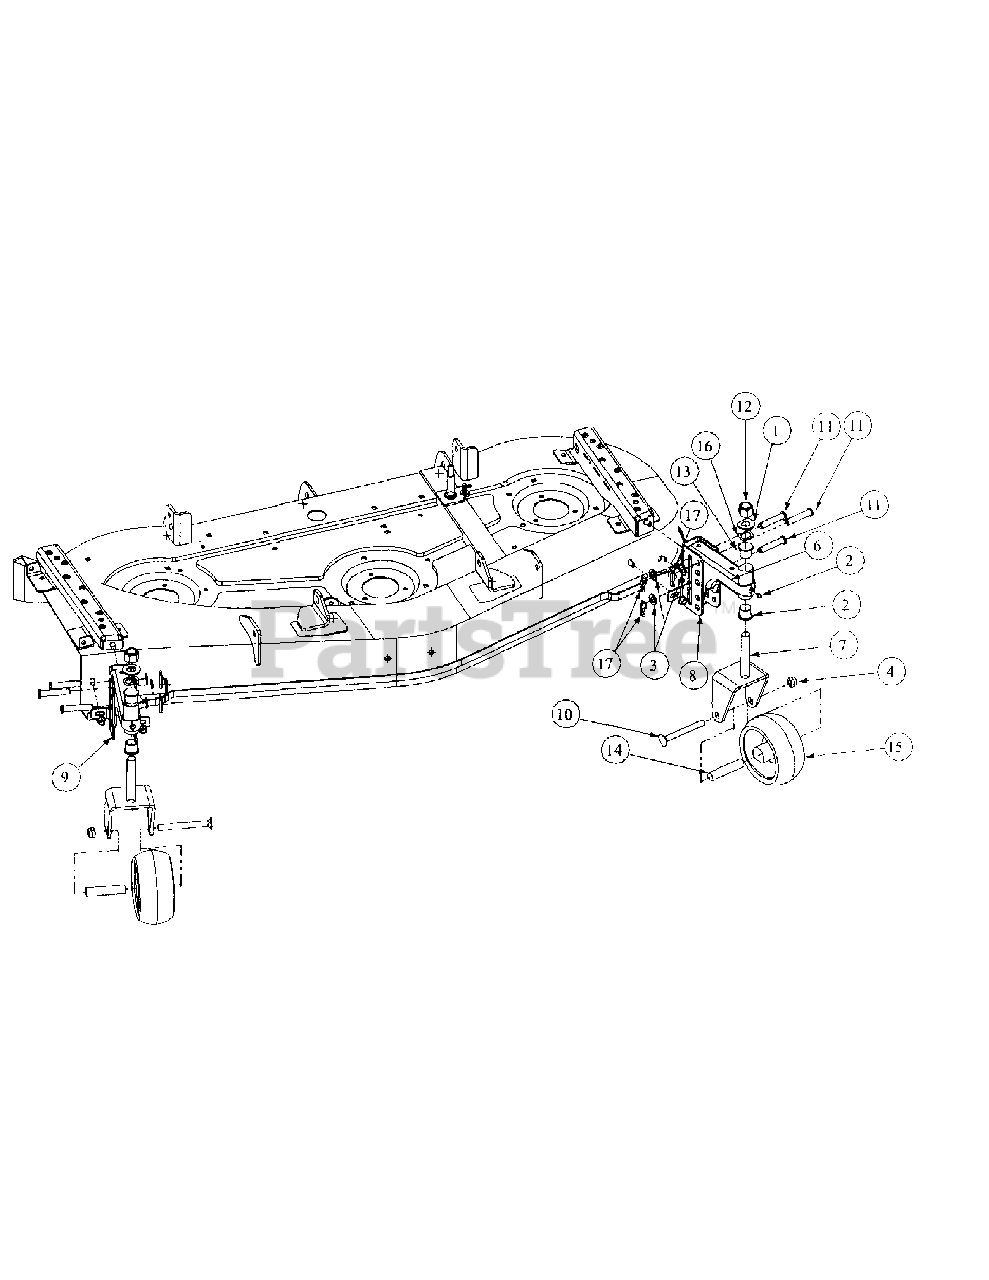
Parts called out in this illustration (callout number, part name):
1	Flat Washer, .750 x 1.50 x .120
2	3/16 Drive Lube, Fitting
3	Flat Washer, .595 ID x .945 x .09
4	Hex Nut, 1/2-13
6	Caster Wheel Arm Assembly
7	Caster Wheel Yoke Assembly
8	Right Hand Height Adjustment, Bracket
9	Height Adjustment Bracket
10	Carriage Screw, 1/2-13, 4.50
11	Clevis Pin, .500 Dia. x 2-1 /2
12	Lock Hex Nut, 3/4-10
13	Bearing Flange, .754 ID x 1.00 OD x.925
14	Caster Wheel Axle
15	Wheel Assembly, 6 x 3.00-4, White
16	Washer, Wave, 1.38 OD x .88 ID x .02
17	Cotter Pin, Internal, .50 Diameter
